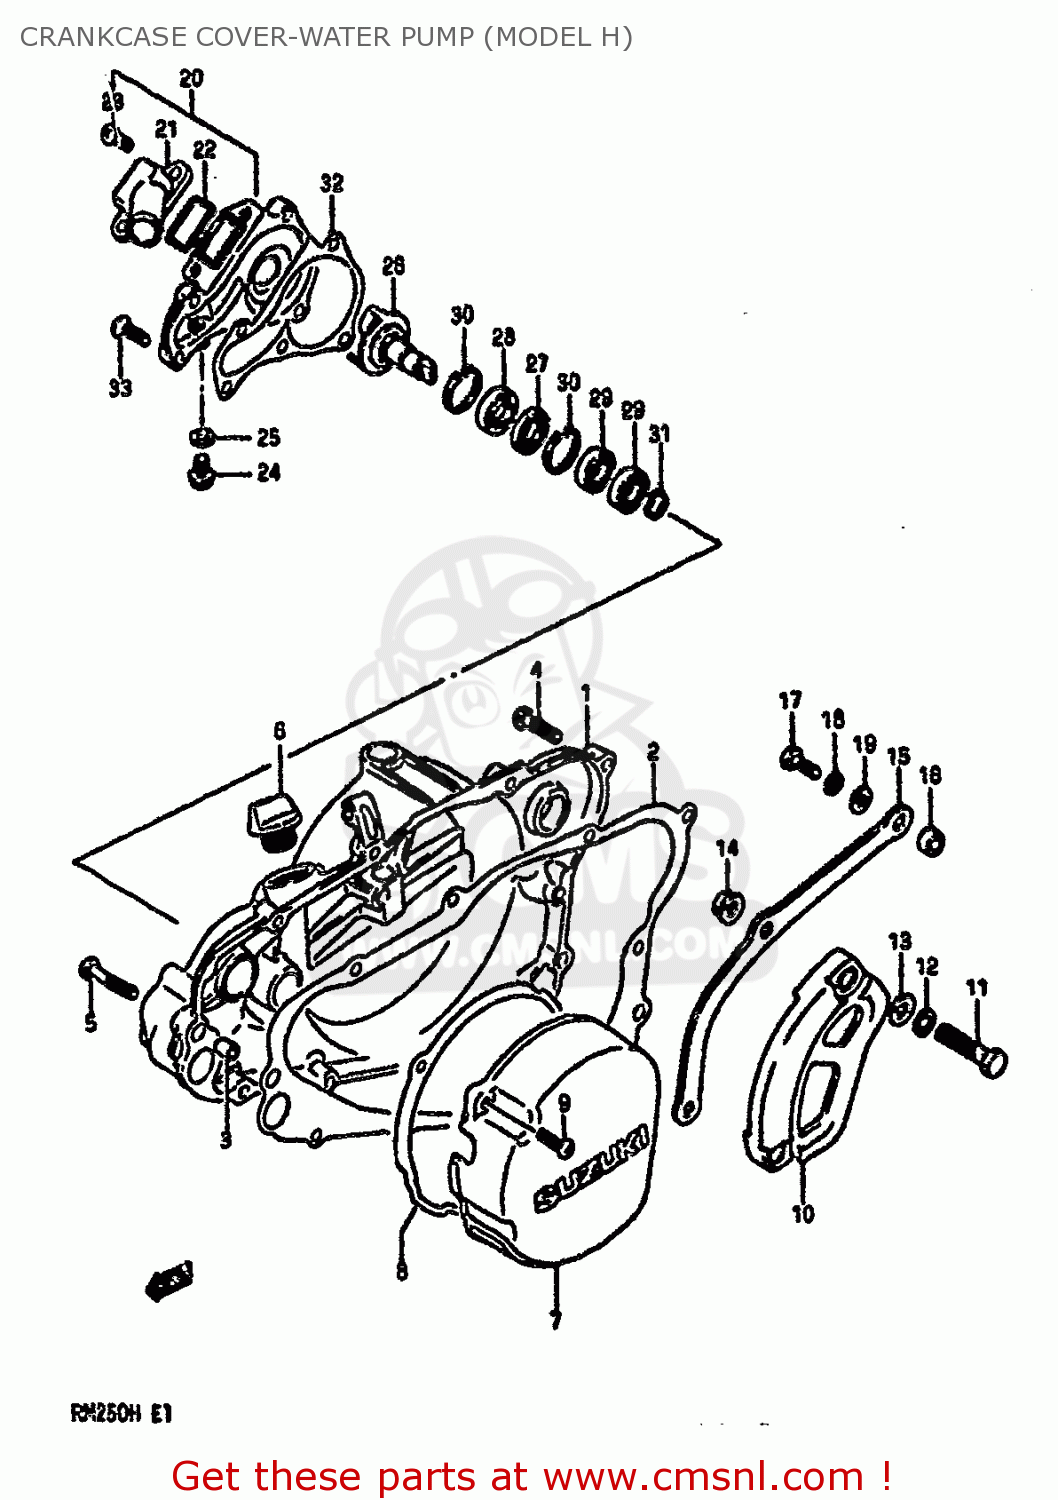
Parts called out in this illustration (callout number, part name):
1	COVER,CLUTCH
2	GASKET,CLUTCH COVER
3	PIN
4	SCREW
5	SCREW
6	PLUG SET
7	COVER,MAGNETO
8	GASKET,MAGNETO COVER (MCA)
9	SCREW
10	COVER,SPROCKET
11	BOLT
12	LOCK WASHER
13	WASHER
14	NUT
15	PLATE,FRONT CHAIN GUIDE
16	SPACER (6.5X12X8)
17	BOLT
18	WASHER,LOCK
19	WASHER
20	CASE ASSEMBLY,WATER PUMP
21	CONNECTOR,WATER INLET
22	O RING,WATER PUMP CONNECTOR
23	SCREW
24	BOLT,DRAIN
25	GASKET 8.2X14X1 (NAS)
26	IMPELLER,WATER PUMP
27	SEAL,OIL(12X24X3.6)
28	SEAL,OIL(12X24X6.4)
29	BEARING(10X22X6)
30	CIRCLIP
31	CIRCLIP,10MM
32	GASKET,WATER PUMP CASE (MCA)
33	SCREW
